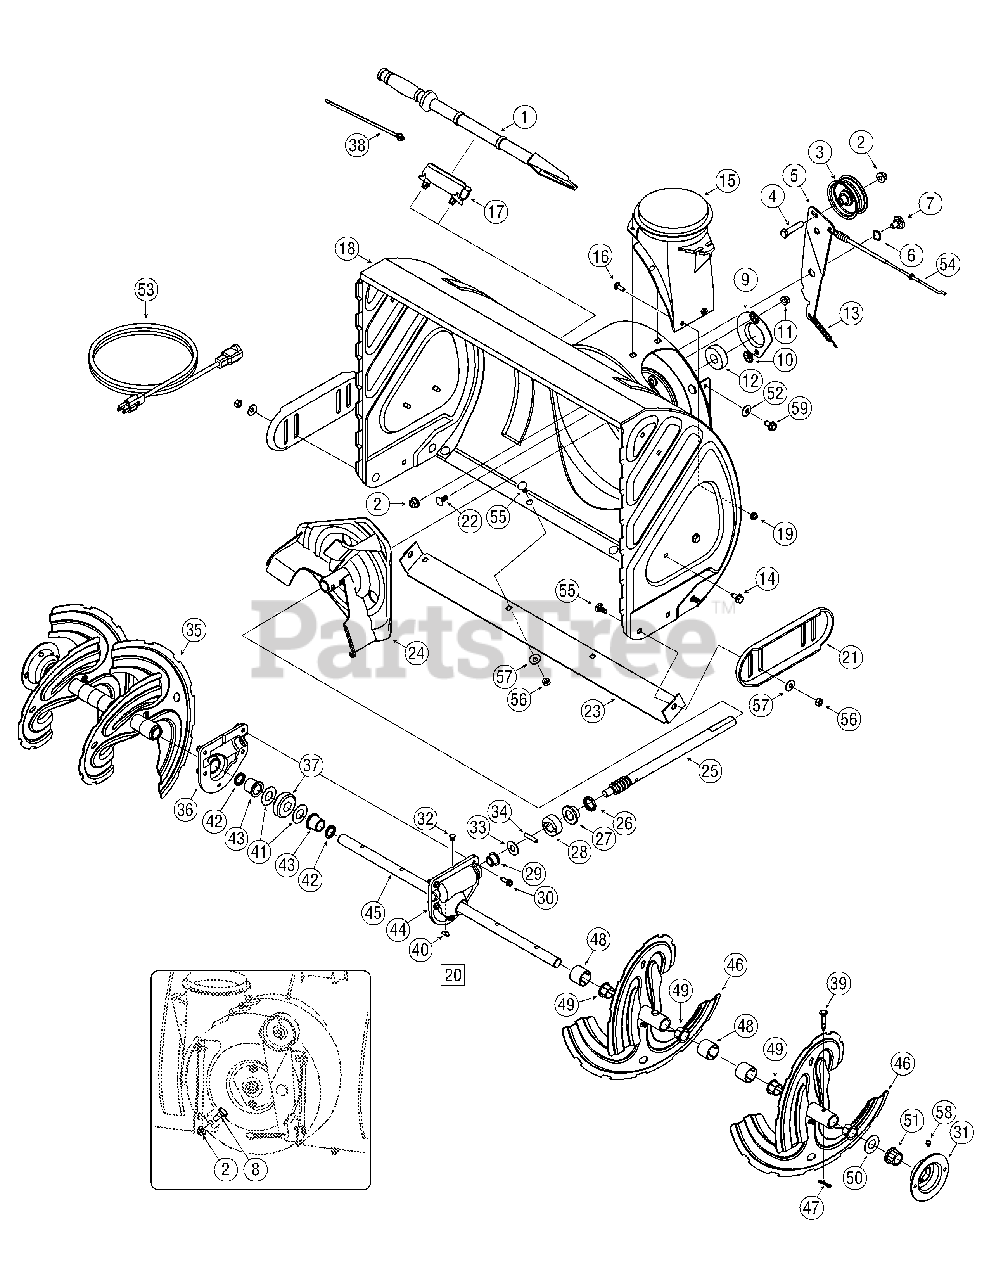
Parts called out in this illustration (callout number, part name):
1	Clean-Out Tool
2	Flange Lock Nut
3	Flat Idler Pulley
4	Hex Bolt, 3/8-16 x 1.75
6	Wave Washer
7	Shoulder Screw
8	Shoulder Screw
9	Bearing Housing
11	Flange Lock Nut, 5/16-18
12	Ball Bearing
13	Extension Spring
14	Screw, 5/16-18 x 0.625
15	Chute Adapter
16	Carriage Screw, 1/4-20 x 0.75
17	Clean-out Tool Mtg. Bracket
20	Gearbox Assembly, 26-inch
21	Slide Shoe, Stainless
22	Carriage Bolt
23	Shave Plate, Stainless, 25.66"
25	Worm Shaft
27	Flange Bearing
28	Thrust Collar
29	Flange Bearing
30	Screw, 1/4-20 x 0.75
33	Flat Washer
36	Reducer Hsg.-RH
37	Worm Gear, 20T
38	Cable Tie
40	Key
41	Flat Washer
43	Flange Bearing
44	Reducer Hsg.- LH
45	Axle, Auger, 26"
47	Bow Tie Cotter Pin
49	Flange Bushing
50	Flat Washer
51	Hex Flange Bearing
52	Bell Washer
53	Extension Cord
54	Auger Clutch Cable
55	Carriage Bolt, 5/16-18 x .750
56	Hex Nut, 5/16-18
57	Bell Washer, .340 x .872 x .060
58	Drive Lube Fitting
59	Screw, 5/16-18 x 0.75
